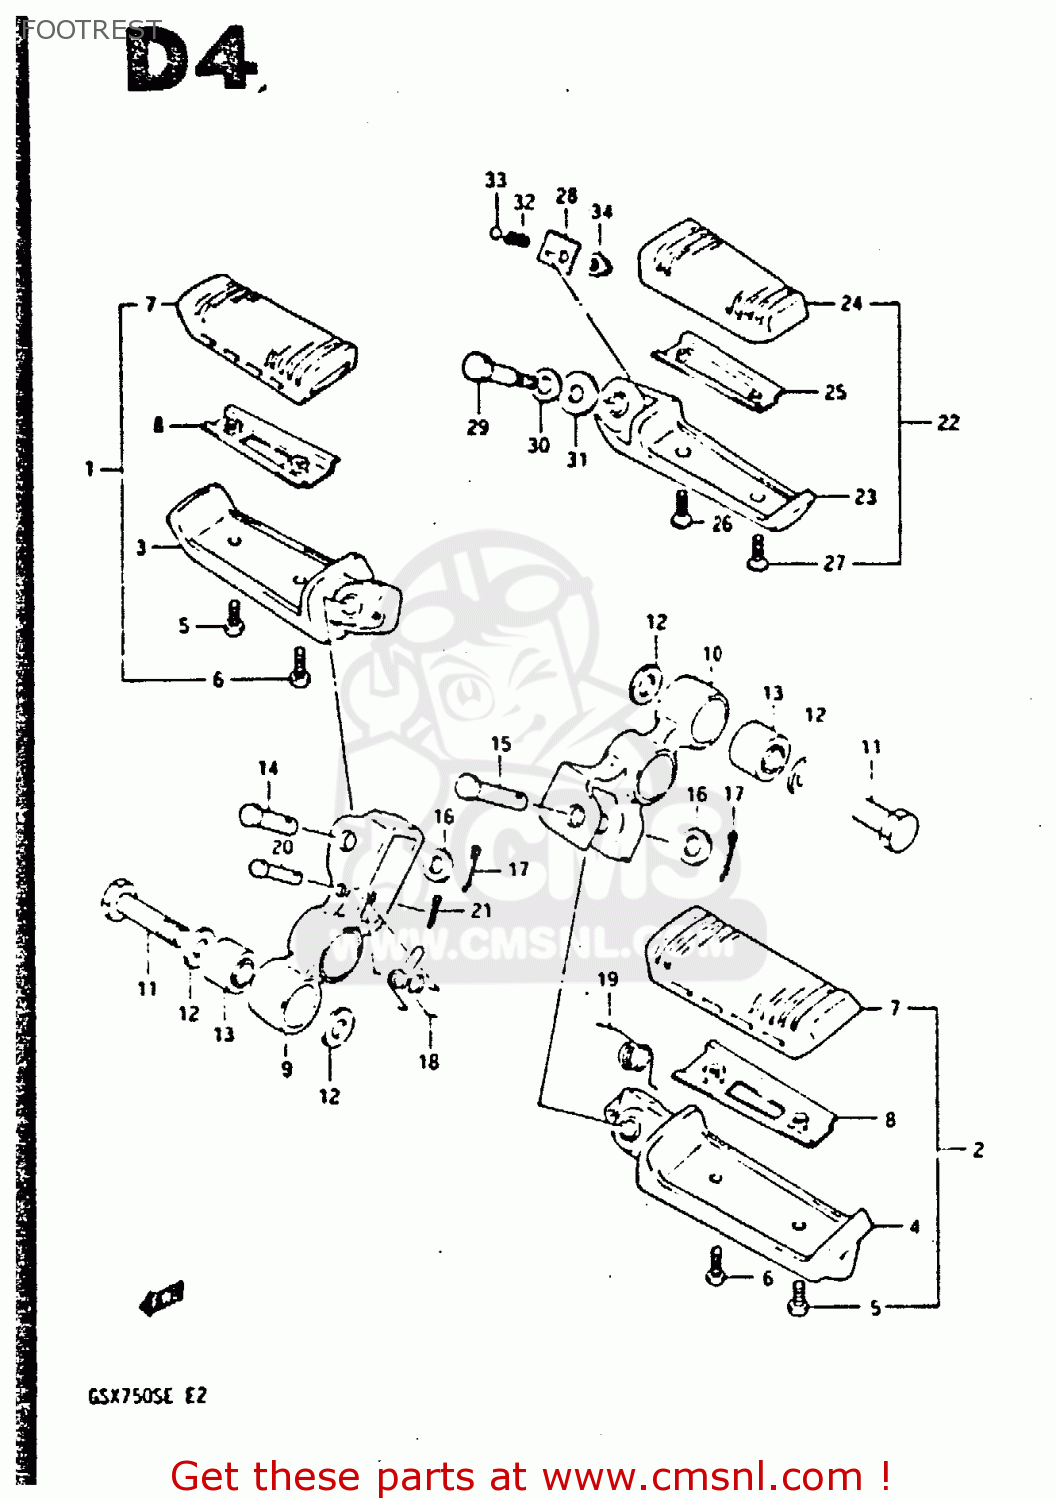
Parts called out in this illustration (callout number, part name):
1	FOOTREST ASSY, FRONT RH
2	FOOTREST ASSY, FRONT LH
3	BAR, FRONT FOOTREST RH
4	BAR, FRONT FOOTREST LH
5	SCREW
6	SCREW
7	RUBBER,FOOTREST
8	PLATE,FR FOOTREST RUBBER
9	HOLDER,FR FOOTREST,R
10	HOLDER, FOOTREST LH (BLACK)
11	BOLT
12	WASHER
13	BUSH
14	PIN
15	PIN, LH
16	WASHER
17	PIN 20X20
18	SPRING
19	SPRING
20	PIN
21	PIN 20X20
22	FOOTREST ASSY, PILLION RH
23	BAR, PILLION FOOTREST RH
24	RUBBER,RR FOOTREST
25	PLATE,RUBBER STOPPER
26	SCREW
27	SCREW
28	PLATE, SPRING STOP RH
29	BOLT
30	SHIM(8.2X22X0.2)
31	WASHER
32	SPRING
33	BALL
34	NUT
